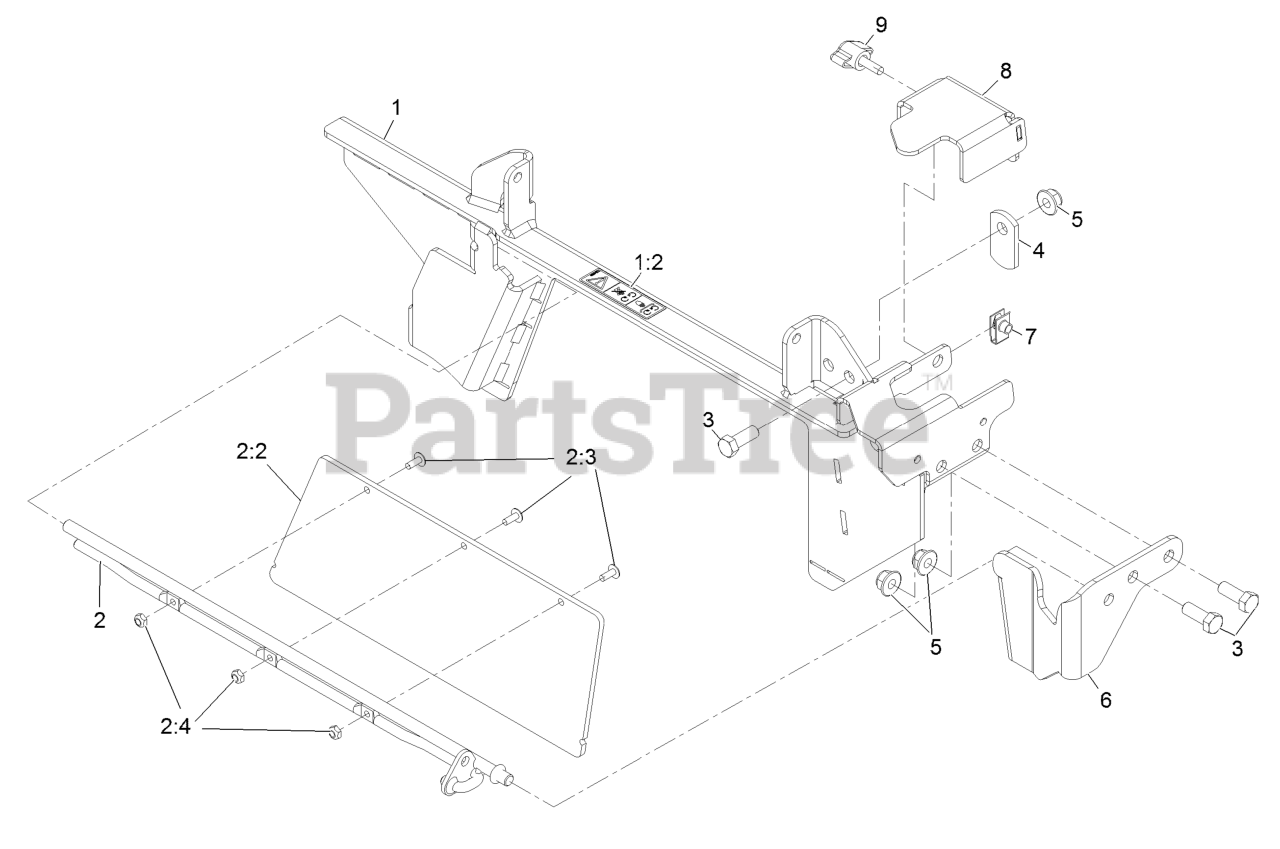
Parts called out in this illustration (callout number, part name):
1	OCD FRAME ASM W/ DECALS
1:2	DECAL, COVER MISSING
2	OCD GATE ASM
2:2	GATE-OCD
2:3	SCREW-PTH
2:4	NUT-LOCK, NI
3	SCREW-HH
4	LATCH-CATCHER, GRASS
5	NUT-HF, NI
6	BRKT,CHUTE FRONT
7	Nut-Retainer-Panel 1/4-20
8	BRACKET, CABLE MOUNT
